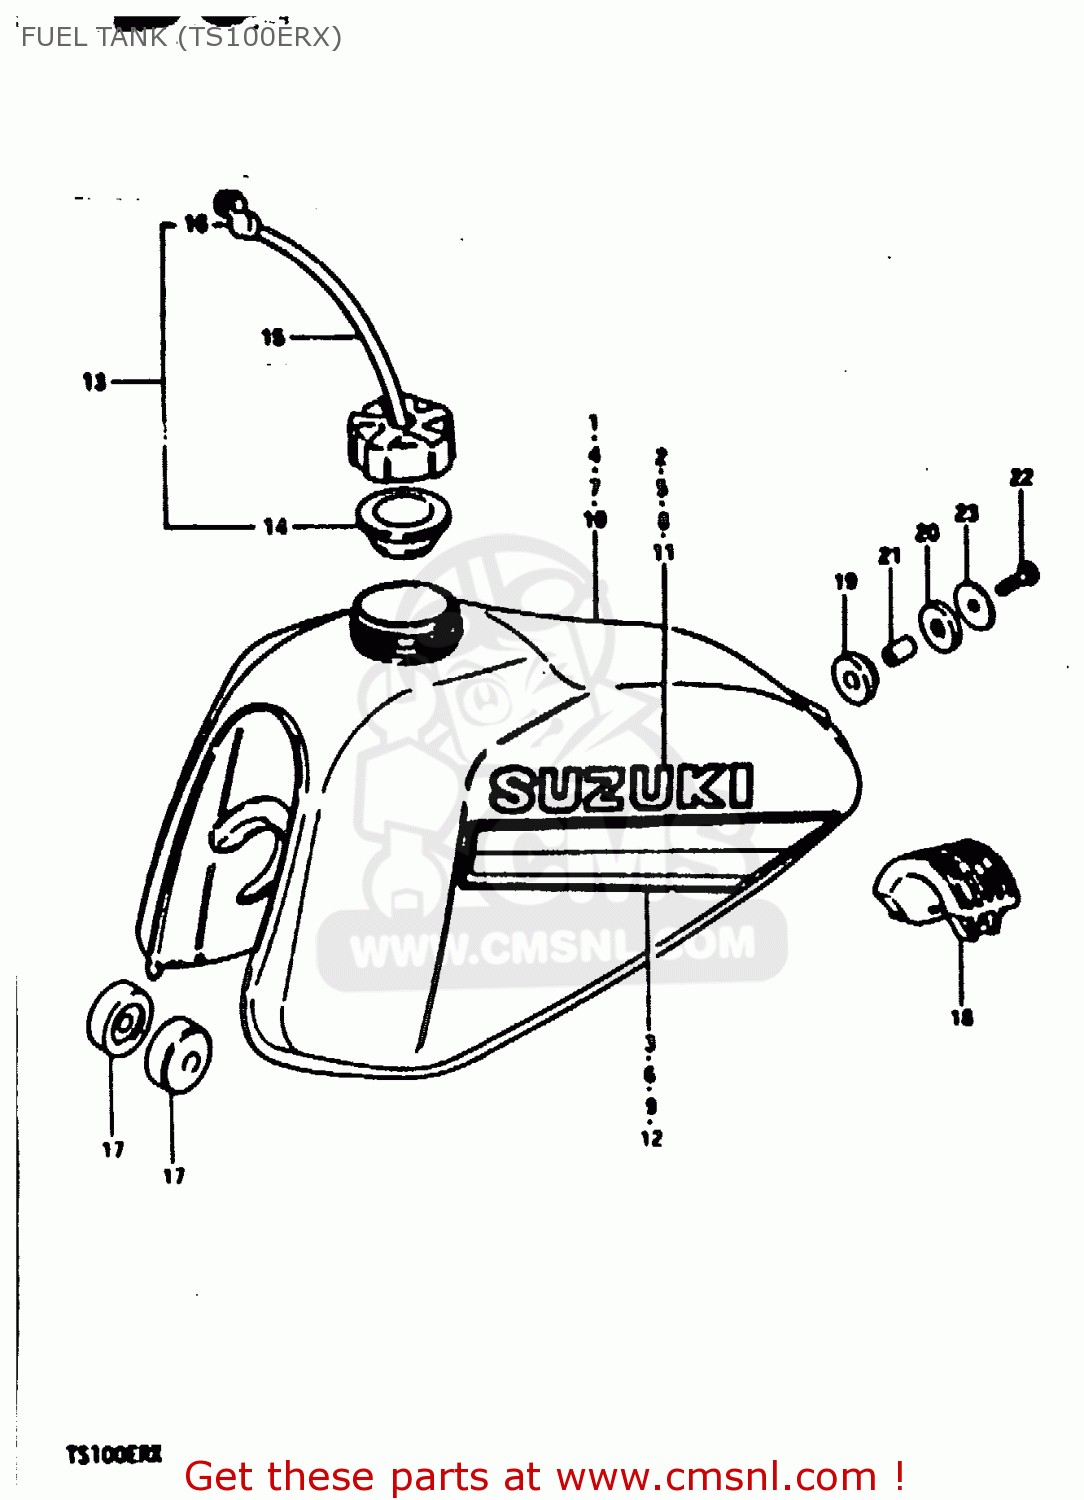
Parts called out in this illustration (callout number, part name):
1	TANK, FUEL (BLUE)
2	EMBLEM
3	TAPE SET
4	TANK, FUEL (YELLOE)
5	EMBLEM(BLACK)
6	TAPE SET
7	TANK, FUEL (RED)
8	EMBLEM
9	TAPE SET
10	TANK, FUEL (WHITE)
11	EMBLEM(BLACK)
12	TAPE SET
13	CAP SET,FUEL TANK
14	GASKET,FUEL TANK CAP (NAS)
15	HOSE
16	CLAMP,FUEL TANK BREATHER HOSE
17	CUSHION
18	CUSHION,FUEL TANK
19	CUSHION
20	CUSHION
21	SPACER(8.5X12X19)
22	BOLT (8X30)
23	WASHER (8.5X29X1.6)
